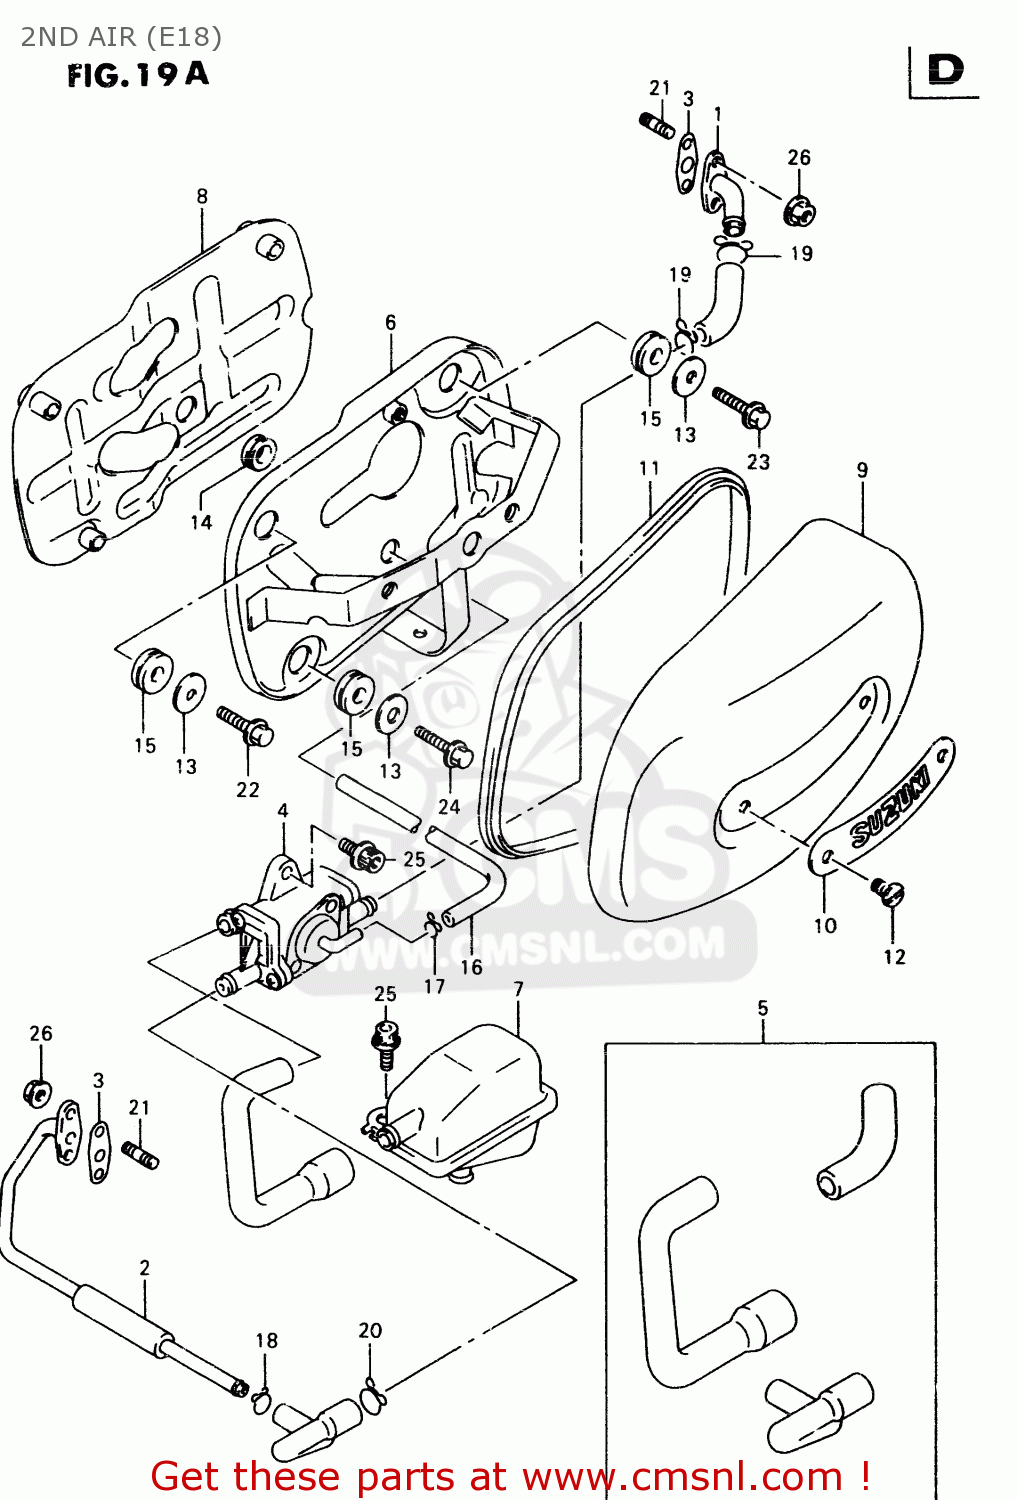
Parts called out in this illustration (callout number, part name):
1	PIPE,2ND AIR FR
2	PIPE,2ND AIR RR
3	GASKET,SECOND AIR PIPE (N (NAS)
4	VALVE ASSY,2ND AIR
5	HOSE SET,2ND AIR
6	BRACKET,2ND AIR SPRT
7	CLEANER,2ND AIR
8	PLATE,2ND AIR HEAT GUARD
9	COVER ASSY,2ND AIR
10	WASHER,2ND AIR COV
11	CUSHION
12	SCREW(6X12)
13	WASHER
14	CUSHION
15	CUSHION
16	HOSE(4X7X600)
17	CLIP
18	CLIP
19	CLIP
20	CLIP
21	STUD BOLT
22	BOLT
23	BOLT
24	BOLT
25	BOLT MAGNETO S
26	NUT
